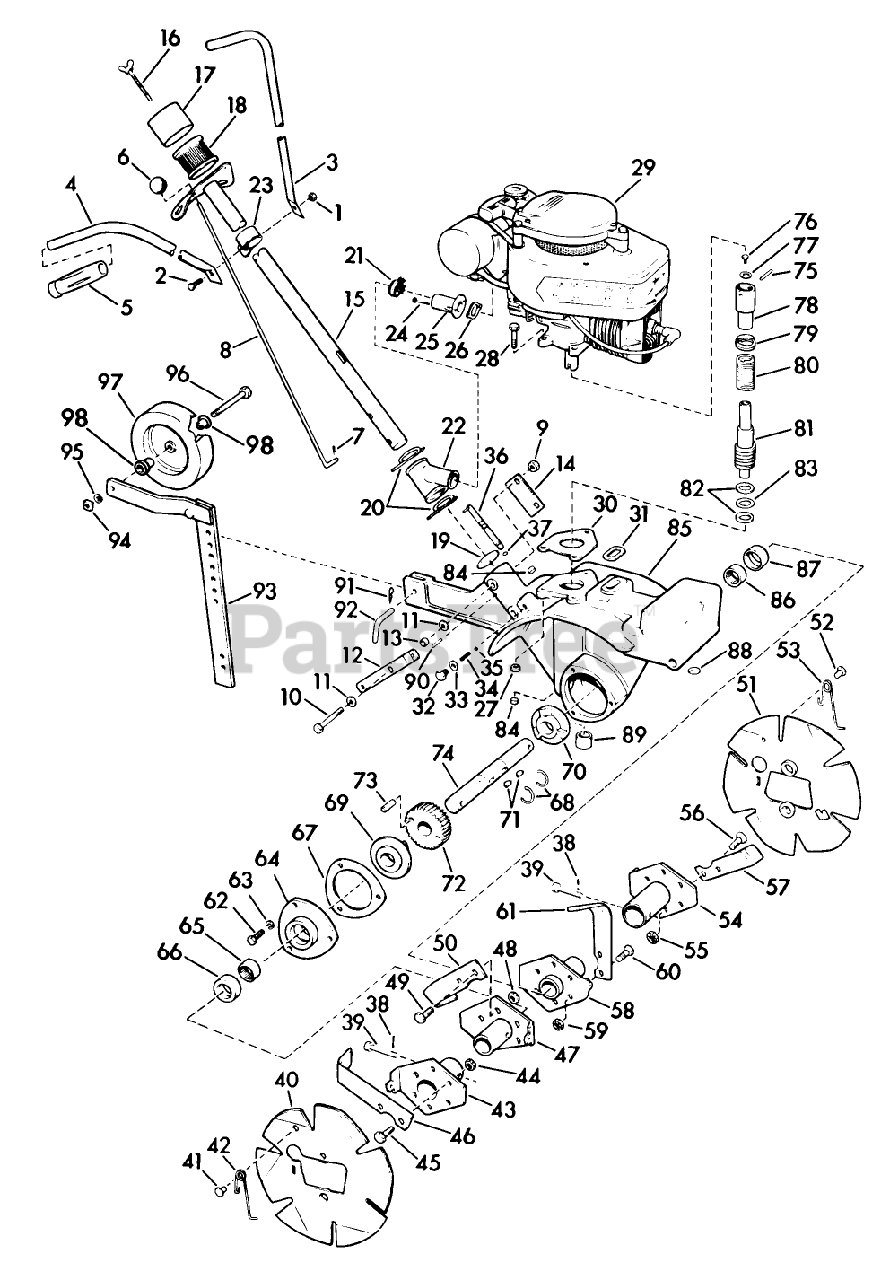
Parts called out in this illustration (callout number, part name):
3	Handlebar Section-Left
4	Handlebar Section-Right
6	Knob-Control Rod
7	Cotter Pin
8	Rod-Control
9	LOCKNUT
10	Screw-Hex Head Cap
12	Cotter Pin
13	Spacer-Control Rod Lever
14	Clamp-Handlebar Support Tube
19	Seal-Dust, Felt
20	Clamp-Hose
22	Tee-Carburetor, Rubber
23	Clamp-Handlebar
25	Tube-Carb. to Handle
32	Screw-Hex Head, Nylok
33	Washer-Plain, Aluminum
34	Spring-Detent
35	Ball-Detent
36	Clutch Pin Control Assy.
37	Ring-"O", Clutch Pin
39	Pin-Tine Assy. Attachment
41	Rivet-Shoulder
42	Spring-Trim Plate, Right
45	Screw-Hex Head Cap
46	Tine-Right Hand
49	Screw-Hex Head Cap
50	Tine-Right Hand
52	Rivet-Shoulder
53	Spring-Trim Plate, Left
56	Screw-Hex Head Cap
57	Tine-Left Hand
60	Screw-Hex Head Cap
61	Tine-Left Hand
65	Bearing
67	Gasket-Housing Cover
68	Ring-Retaining
70	Ratchet-Clutch, Left
72	Gear-Worm
73	Pin-Ratchet
74	Shaft-Worm Gear
75	Pin-Clutch
76	Screw-Hex Head, Nylok
77	Washer-Thrust
78	Coupling-Clutch Drum
79	Spring-Clutch Shock
82	Race-Thrust
83	Bearing-Needle Thrust
86	Bearing
89	Bearing-Closed End
92	Pin-Selector
95	WASHER, LOCK
